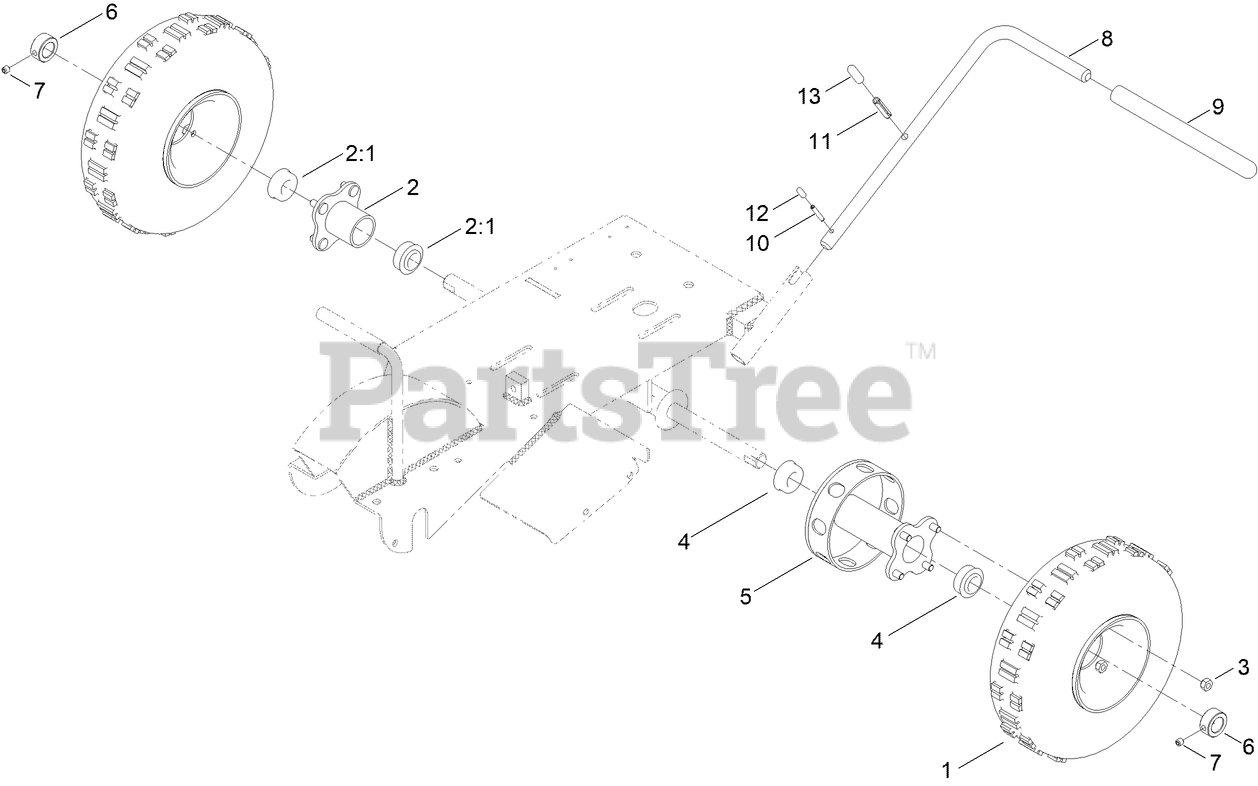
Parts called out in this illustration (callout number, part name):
1	WHEEL AND TIRE ASM
2:1	BEARING-WHEEL
3	NUT-WHEEL
4	BEARING-WHEEL
5	BRAKE HUB RING ASM [BLK-TXT]
6	COLLAR-SET
7	SCREW-SET, HSH
8	HANDLE-BRAKE
10	PIN-ROLL, SLOTTED
11	PIN-ROLL
12	CAP-LOWER
13	CAP-UPPER
